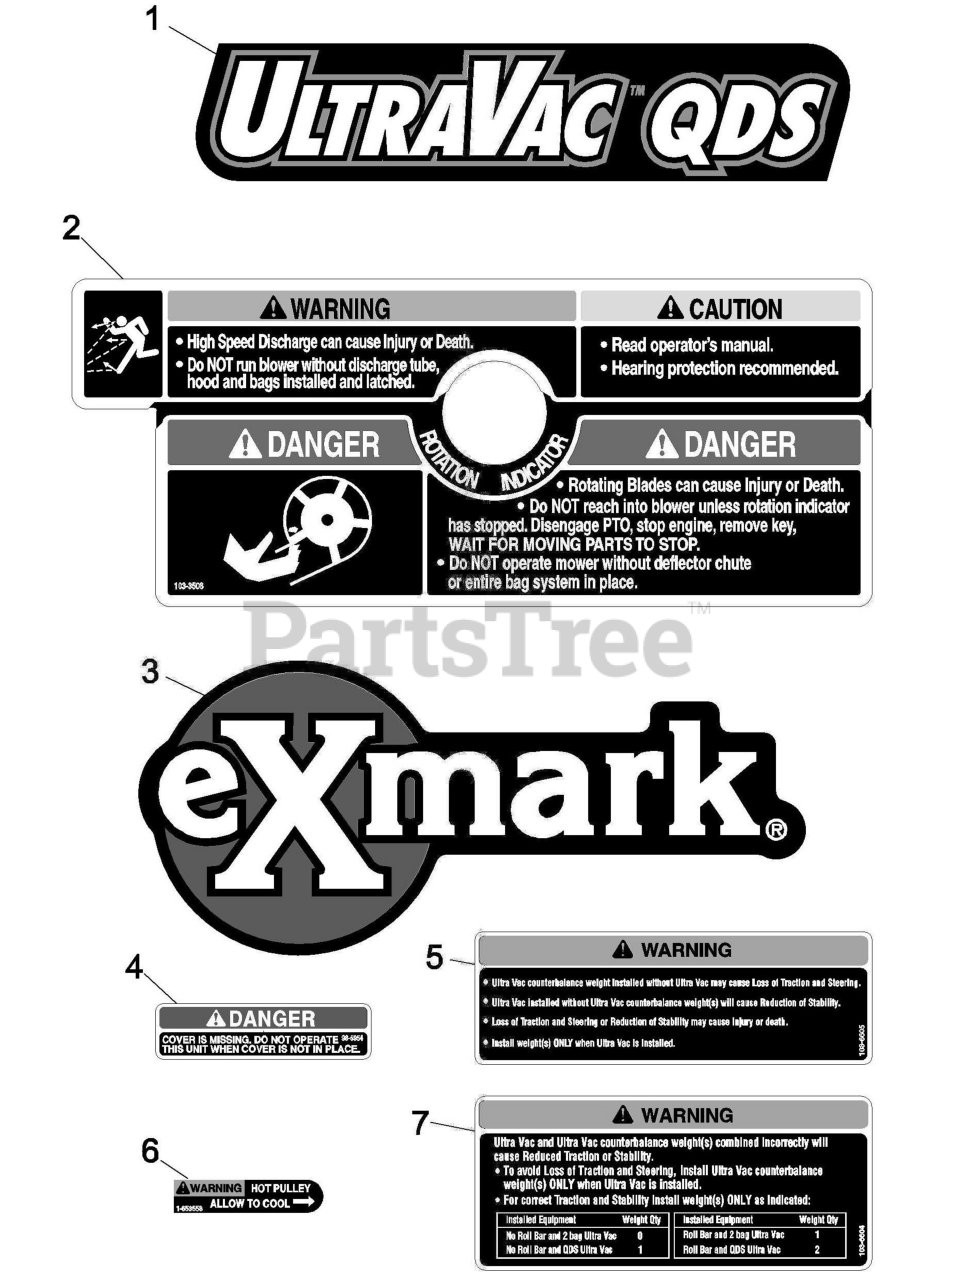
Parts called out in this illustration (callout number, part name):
1	DECAL, ULTRAVAC QDS
2	DECAL-WARNING
3	DECAL, EXMARK LOGO
4	DECAL-COVER, MISSING
5	DECAL,WEIGHT
6	DECAL-WARNING
7	DECAL,WEIGHT
